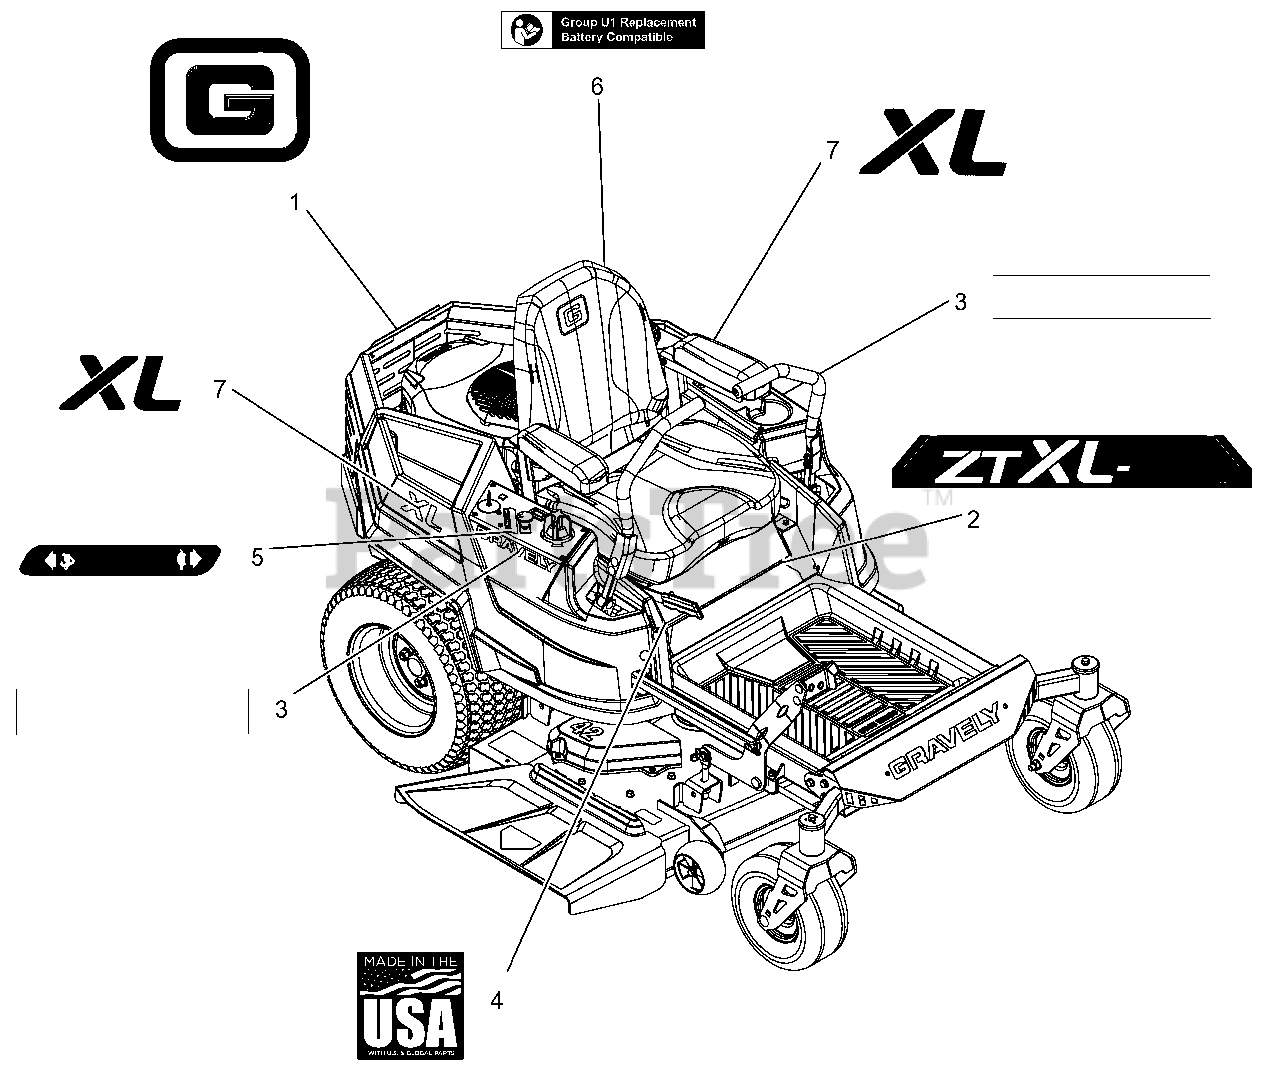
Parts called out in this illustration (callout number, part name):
1	DECAL, GRAVELY BRAND
2	DECAL, ZT XL 42"
3	DECAL, 9.5" GRAVELY LOGO
4	DECAL, MADE IN USA
5	DECAL, DASH DECAL
6	DECAL, U1 BATTERY REPLACEMENT
7	DECAL, "XL"
